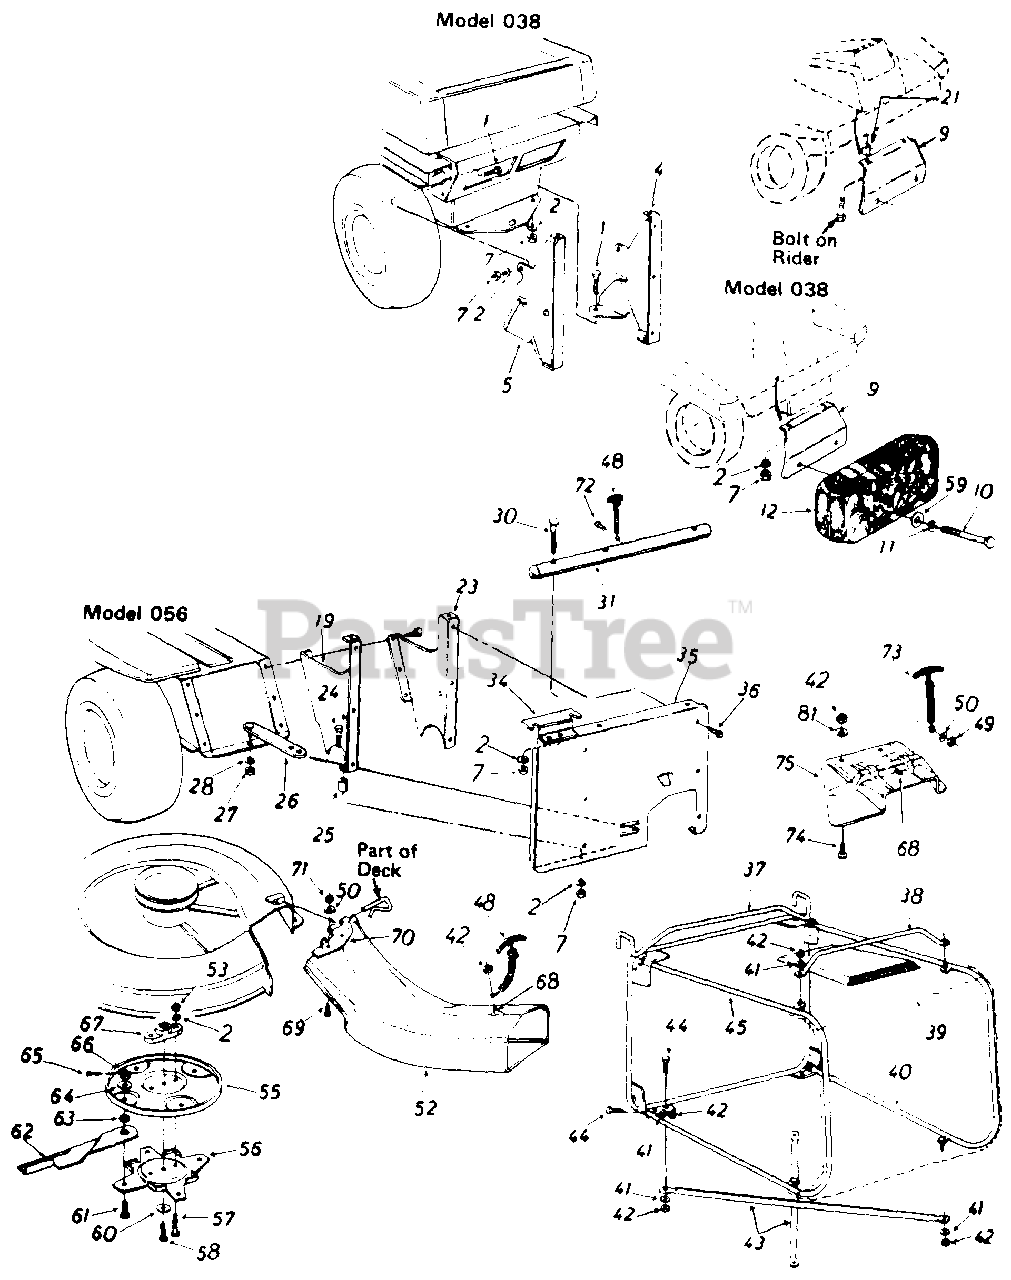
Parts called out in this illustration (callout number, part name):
1	Hex Bolt 5/16-18 x 1" Lg.
2	L-Wash. 5/16" I.D.
4	Catcher Support Brkt.- R.H.
5	Catcher Support Brkt.- L.H.
7	Hex Nut 5/16-18 Thd.
9	Counterweight Support Brkt. Ass'y.
10	Hex Bolt 3/8-16 x 4.5" Lg.
11	Bell-Wash. .40" I.D. x .88" O.D.
12	Counterweight 38 lbs.
19	Catcher Support Brkt.- L.H.
21	Spacer .380" I.D. x 1" O.D. x .32" Lg.
23	Catcher Support Bkrt.- R.H.
24	Hex Bolt 5/16-18 x 1.5" Lg.
25	Spacer .38" I.D. x .47" O.D. x 1" Lg.
28	L-Wash. 1/2" I.D.
30	Curved Carriage Bolt 5/16-18 x 1.75" Lg.
35	Rear Discharge Panel
36	Hex Wash. Hd. Self-Tap Scr. 1/4-20 x .5" Lg.
37	Grass Catcher Frame Ass'y.
42	Hex L-Nut 1/2-20 Thd.
43	Bottom Cross Brace
44	Hex Bolt 1/4-20 x .62" Lg.
50	L-Wash. 1/4" I.D.
52	R.D. Banana Chute Ass'y.
53	Hex Nut 5/16-24 Thd.
55	Upper Blade Disc
58	Hex Bolt 3/8-24 x 1.0" Lg.
59	Fl-Wash. .39" I.D. x 1.12" O.D.
60	Bell-Wash. .39" I.D. x 1.38"
61	Shld. Bolt .50" Dia. x .36"
62	30" Blade Tip
63	Spacer .505" I.D. x .75" O.D. x 1.25" Lg.
64	Fl-Wash. .5" I.D. x 1.25" O.D.
65	Cotter Pin 3/32" Dia. x 1" Lg.
66	Hex Slotted Nut 1/2-20 Thd.
67	Blade Adapter
68	Hex Bolt 1/4-20 x .5" Lg.
69	Truss Mach. Scr. 1/4-20 x .5" Lg.
72	Hex AS-Tap Scr. 1/4 x .62" Lg.
73	Hook Latch Ass'y.
74	Truss Mach. Scr. 1/4-20 x .50" Lg.
75	R.D. Chute Extension
81	Fl-Wash. .281" I.D. x .50" O.D. x .063
